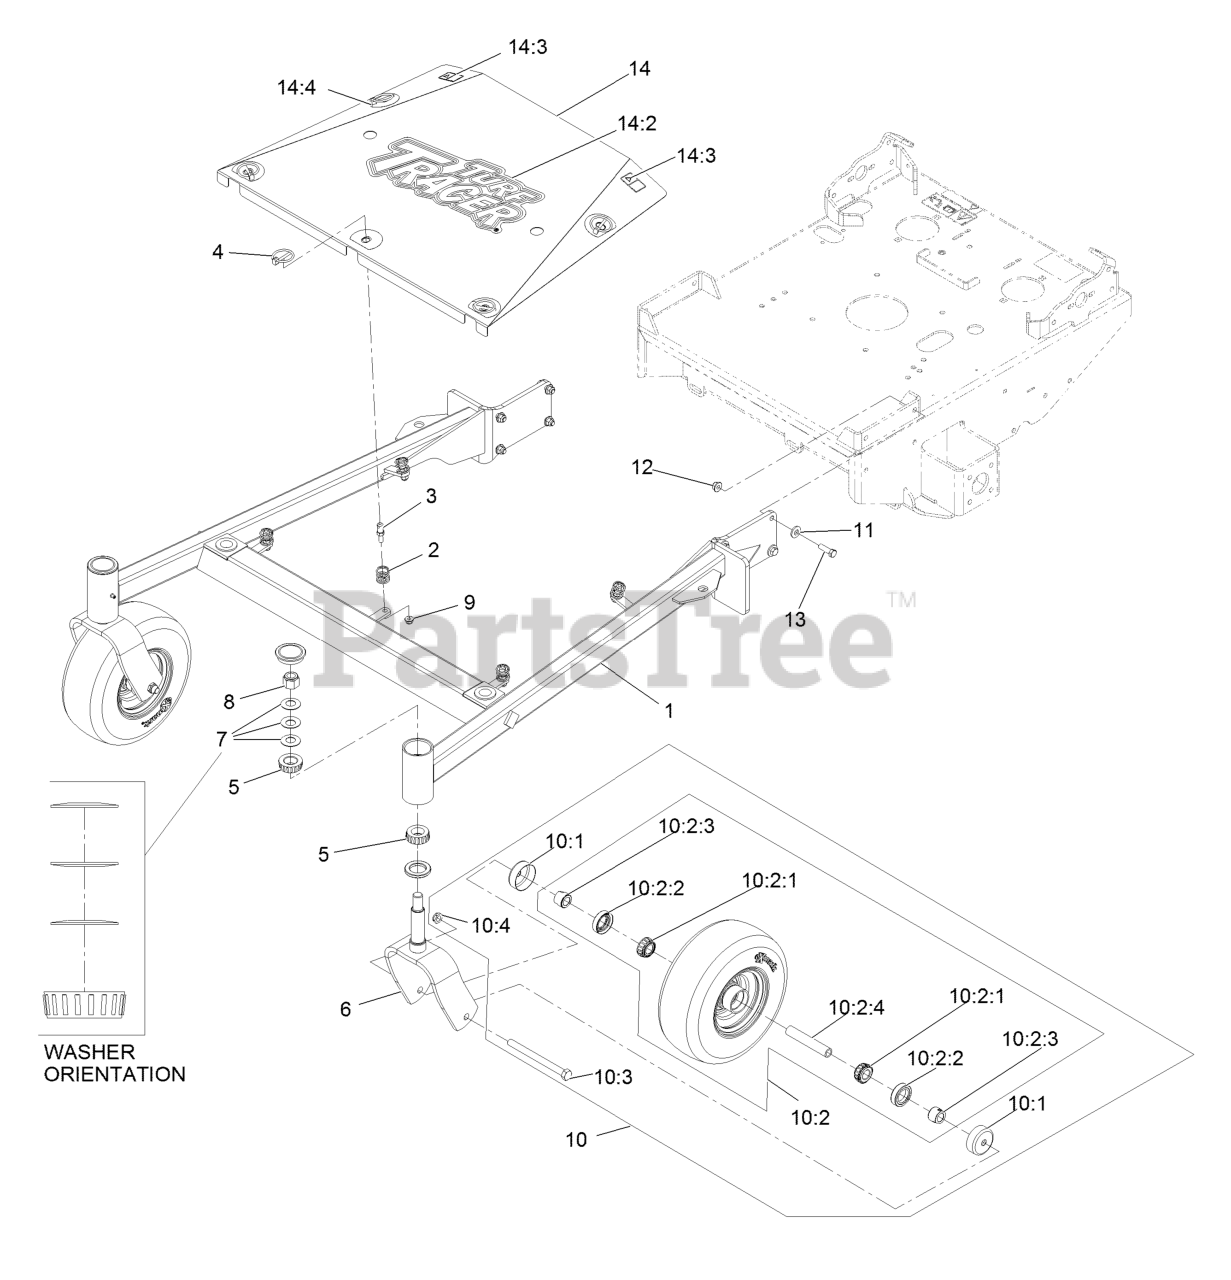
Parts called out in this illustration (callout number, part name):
1	ASM, FRONT FRAME W/ BEARI
3	PIN-SPRING
4	PIN-LYNCH
5	Cone-Bearing Tapered Roller
6	WLD, CASTER FORK
7	WASHER-BELLVILLE
8	NUT-LOCK, NI
9	NUT-HF, NI
10	ASM,WHEEL&BEARINGS
10:1	GUARD-SEAL
10:2	ASM,Wheel And Bearing
10:2:1	BEARING-CONE, TAPERED ROLLER
10:2:2	SEAL-CASTER
10:2:3	SPACER-NUT
10:3	SCREW-HH
10:4	NUT-HEX
11	WASHER-BELLEVILLE
12	NUT-HF, NI
13	SCREW-HH
14	ASM, CENTER SHIELD W/ DEC
14:2	DECAL,TTH MODEL
14:3	DECAL-WARNING
14:4	DECAL-SCRATCH COVER
